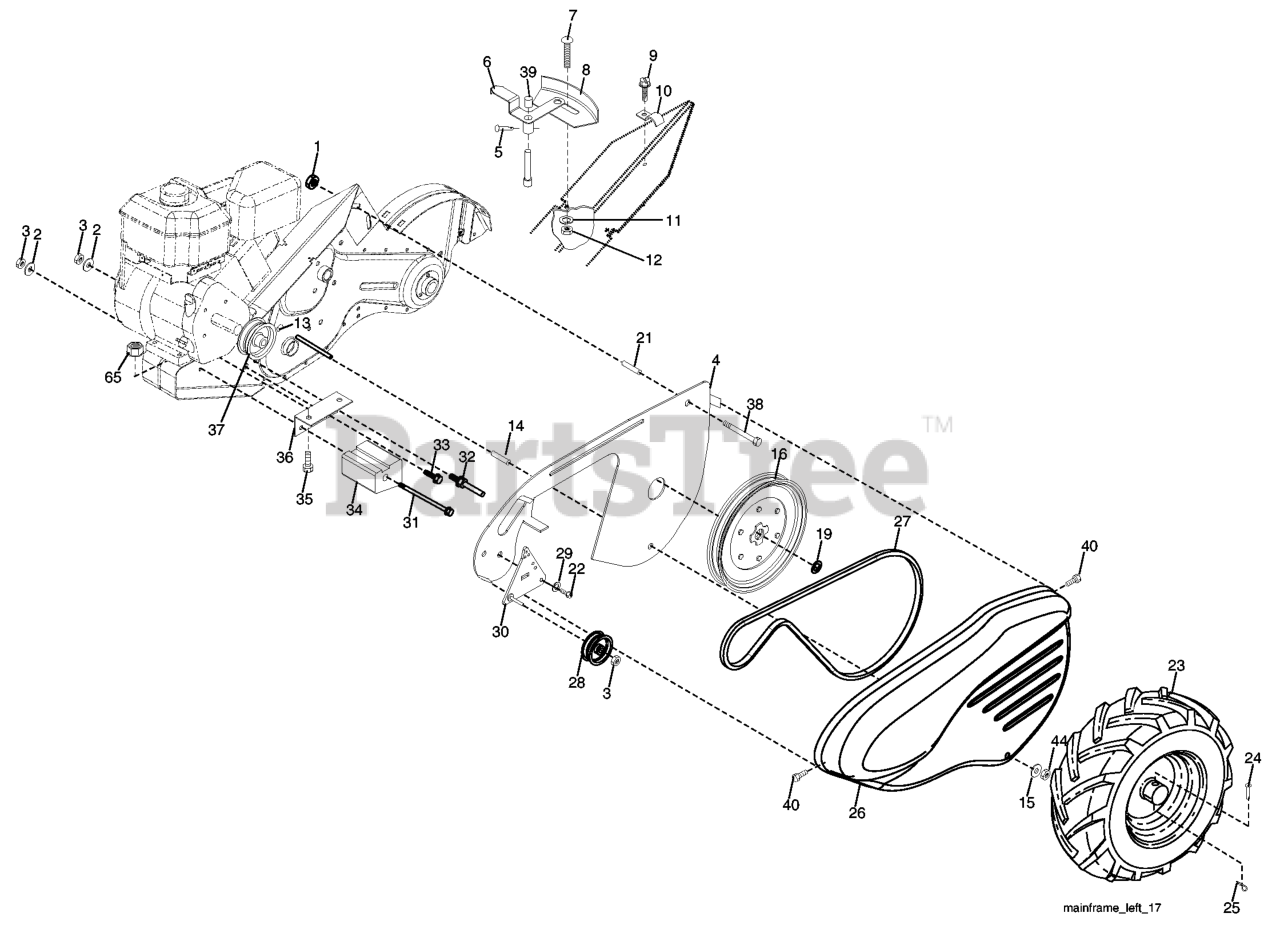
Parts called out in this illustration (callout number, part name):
1	NUT
2	WASHER, LOCK 3/8
3	NUT.HEX.3/8-16UNC
4	SHIELD
5	PIN.SPIROL.FLARED
6	LEVER ASM CRT
8	PANEL.INDICATOR.SHIFT.BLACK
9	TAPPING SCREW
10	CONDUIT.CLIP.PLATED
11	LOCKWASHER
12	NUT
14	SPACER CRT
15	WASHER
16	SHEAVE, TRANSMISSION
19	RETAINING RING LT
21	SPACER-SPLIT.327 X .42
23	TIRE.16X4-8.CHEVRON.TILLER
23	RIM
23	VALVE STEM LT
24	RIVET,DRILLED
25	RETAINER M
26	RP BELT GUARD
27	V-BELT
28	PULLEY-IDLER TI
30	BRACKET.ASM.IDLER.BLACK
31	BOLT.FIN.HEX.3/8-16UNC
32	SHIFT ARM CRT
33	BOLT
34	COUNTERWEIGHT.LH.CRT
35	BOLT
36	BRACKET LH CRT
37	RP.ENGINE PULLEY
38	BOLT
39	CAP.PLUNGER.BLACK
40	SCREW.HEX.WSH.SLT.#10-24X.50
44	NUT.71038.31-18.HEX.NYLOCK
65	LOCKNUT-FLANGE 5/16-18
